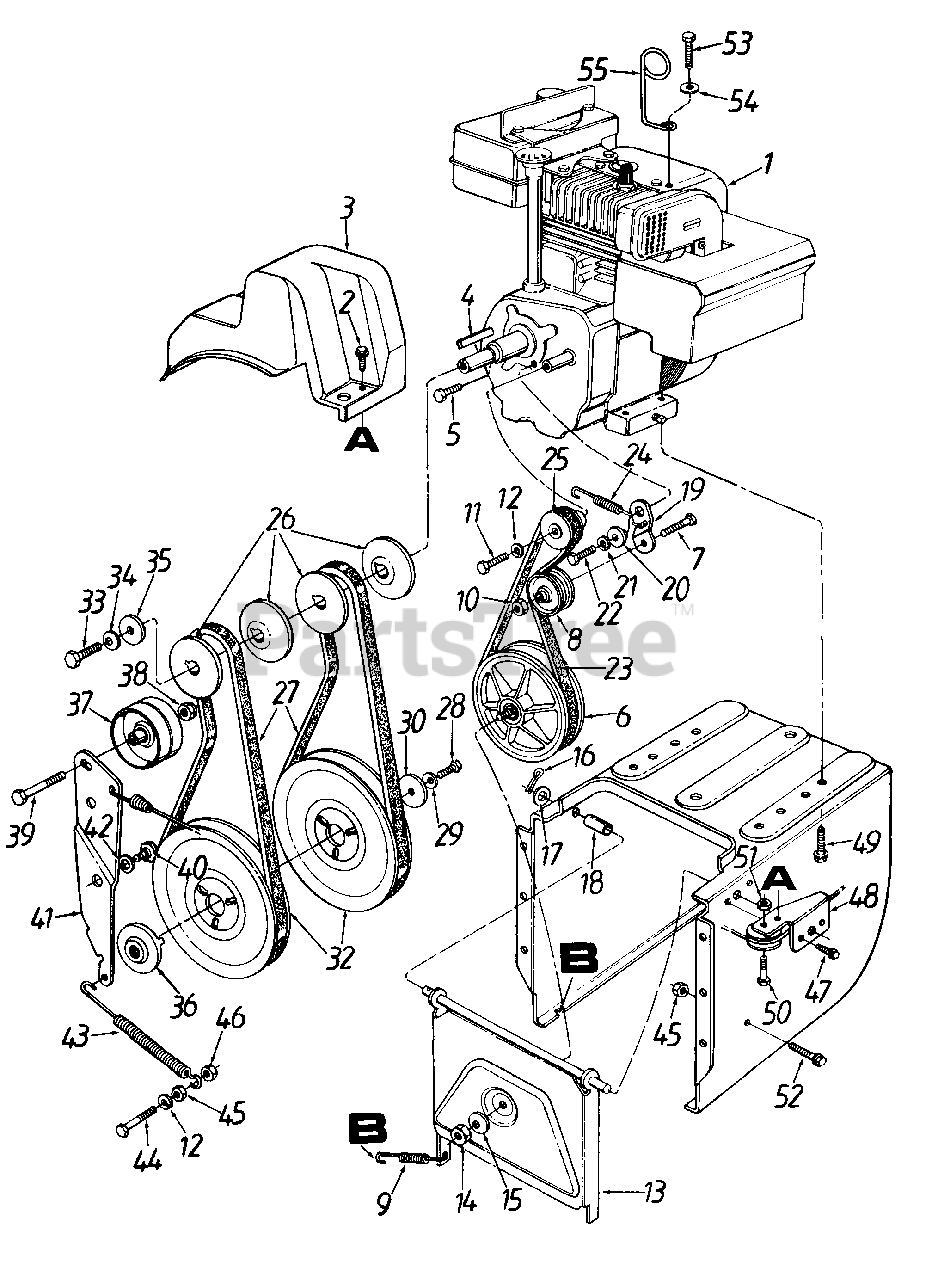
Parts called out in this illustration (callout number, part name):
1	Engine
2	Hex Wash. Hd. TT-Tap Scr. 1/4-20 x .5" Lg.
4	Sq.-Key 3/16 x 1.5" Lg.
5	Hex Patch Bolt 5/16-24 x 1" Lg. (Gr. 5)
6	Friction Wheel Disc Ass'y.
7	Hex Bolt 3/8-16 x 1.25" Lg.
8	Fl-Idler 2.12" O.D.
9	Ext. Spring 2.5" Lg.
10	Hex Top L-Nut 3/8-16 Thd.
11	Hex Bolt 1/4-28 x .5" Lg.
12	L-Wash. 1/4" I.D.
15	Bell-Wash. .38" I.D. x .88" O.D.
16	Cotter Pin 1/8" x .75" Lg.
17	Fl-Wash. .531" I.D. x .93" O.D.
18	Spacer .508" I.D. x .75" O.D.
19	Drive Clutch Idler Bracket
20	Shld. Spacer .5" Dia. x .27" Lg.
22	Hex Wash. Hd. Tap Scr. 5/16-18 x .62" Lg.
23	"V"-Belt
24	Extension Spring
25	2" Dia. Pulley
26	3/8 "V"-Pulley Half
27	"V"-Belt
28	Hex Cap L-Bolt 5/16-24 x .75" Lg.
29	Bell-Wash. 345" I.D. x .88" O.D.
30	Fl-Wash .34" I.D x 1.5" O.D.
32	Auger Pulley
33	Hex Bolt 3/8-24 x .88" Lg.
34	Bell-Wash .39" I D. x 1.13" O.D.
35	Fl-Wash .406" I.D. x 1.25" O.D.
36	Adapter Pulley
37	Fl-Idler 2.75" O.D.
38	Hex Ins. L-Nut 3/8-24 Thd.
39	Hex Bolt 3/8-24 x 1.5" Lg. (Gr. 5)
40	Shld. Bolt .625" Dia. x 170" Lg.
42	Wave Wash. .66" I.D. x 88"
43	Ext. Spring 3.6" Lg.
44	Hex Bolt 1/4-20 x .75" Lg (Gr. 5)
45	Hex Nut 1/4-20 Thd.
46	Hex L-Nut 1/4-20 Thd.
47	Torx Mach. AB-Tap Scr. 1/4 x .62" Lg.
50	Shld. Bolt 5/16" Dia. x .35" Lg.
51	Hex Jam Nut 1/4-20 Thd.
52	Hex Wash. Hd. TT-Tap Scr. 1/4-20 x 1" Lg.
53	Hex Wash. Hd. Tap Scr. 5/16-18 x 1" Lg.
54	Fl-Wash. .349" I.D. x .879" O.D.
55	Cable Control Wire
